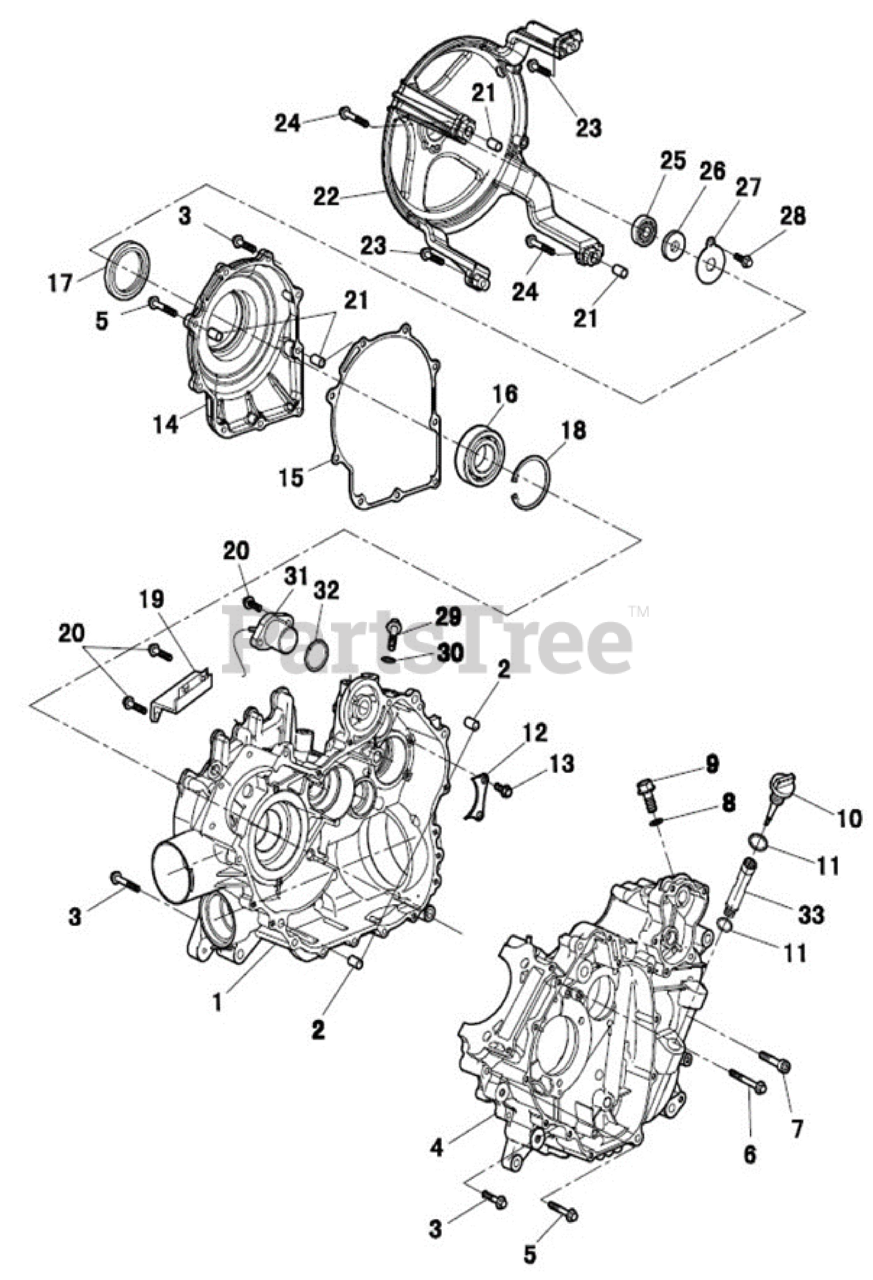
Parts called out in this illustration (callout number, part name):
1	Right Crankcase Assy
2	Pin,Dowel 9X12X16
3	Hexagon flange bolts M6X30
4	Left Crankcase Assy
5	Hexagon flange bolts M6X40
6	Hexagon flange bolts M6X85
7	Hexagon socket head cap screws M8X40
8	Aluminum Washer 14X20X1.5
9	Hexagon flange Screw Plug M14X1.5X16
10	Plug,Oil Level
11	O-Ring 18X3.5
12	Press Plate,Main Shaft Bearing
13	Hexagon flange bolts M6X16
14	Bearing Block,outer cover
15	Gasket,Bearing Block
16	Bearing 16010
17	Oil Seal 35X65X9
18	Circlip for hole 80
19	Bracket,CVT Vent-Pipe
20	Hexagon head bolt and plain washer assemblies M6X16
21	Pin,Dowel 10X16
22	Shield Bracket,Clutch
23	Hexagon flange bolts M6X32
24	Hexagon flange bolts M6X40
25	Bearing 62012Z
26	Oil Seal 12X32X6
27	Press Plate,Bracket oil seal
28	Hexagon flange bolts M6X12
29	Hexagon flange bolts M10X1.25X16
30	Copper Washer 10X16X1
31	Sensor,Gear Indicator
32	O-Ring 29.6X2.4
33	Extended Oil Dipstick Pipe
